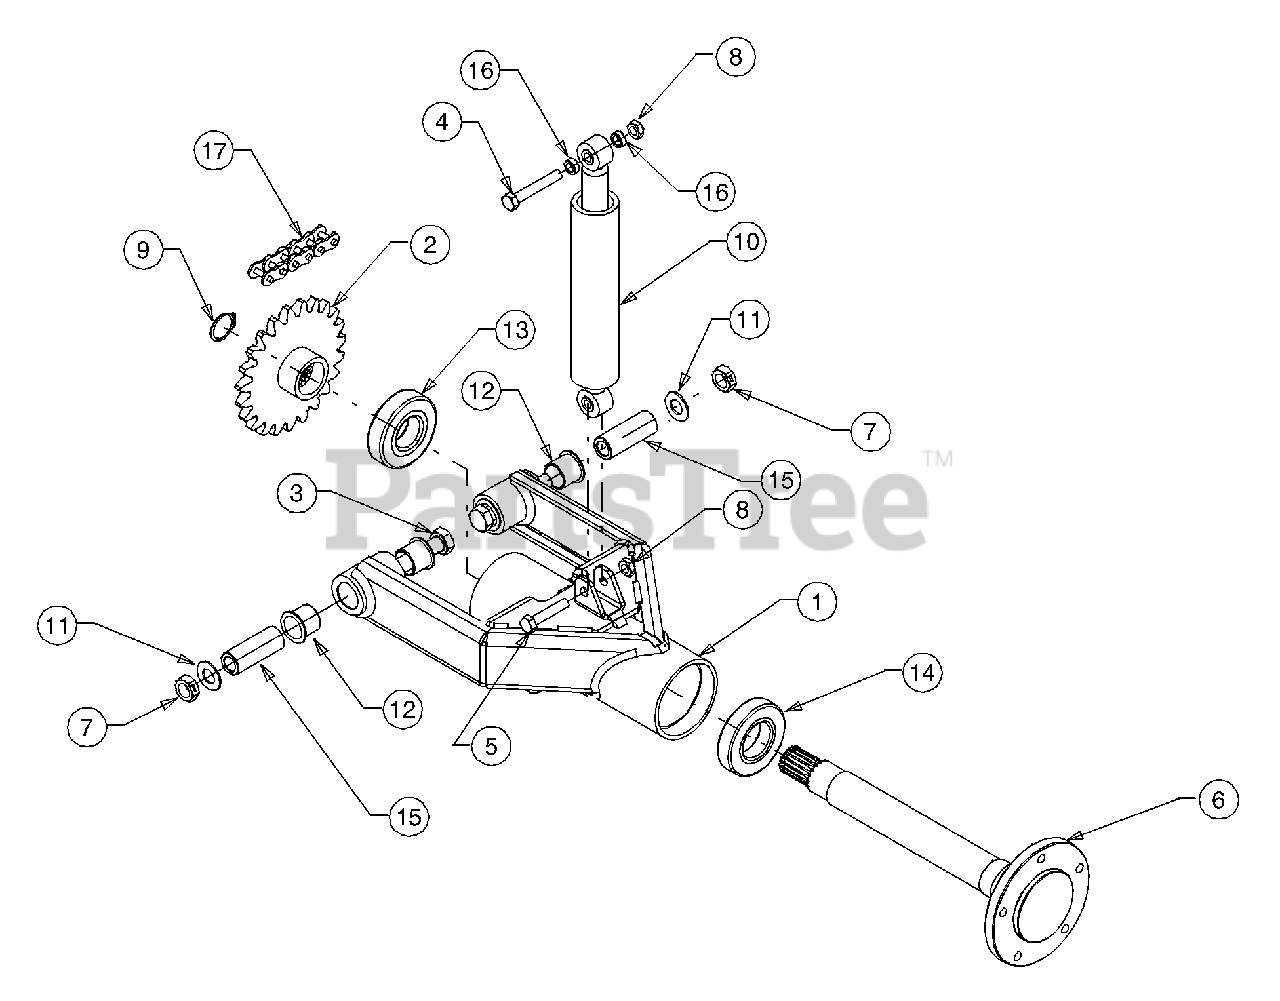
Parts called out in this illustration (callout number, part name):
1	Axle Support Assembly, Rear Weld
2	Sprocket Assembly, Rear, .75 - 23T
3	Screw, Hex, 5/8-18 x 3.5, Gr5
4	Screw, M10-1.25 x .65, Gr8
5	Screw, M10-1.25 x .50, Gr8
6	Axle Shaft, Rear Drive
7	Jam Nut, Nylon Lock, 5/8-18
8	Nut, Nylon Lock, M10 x 1.25
9	Retaining Ring, External, 1.14
10	Shock Absorber, 2.88 Stroke
11	Washer, Flat, .65 x 1.25 x .075
12	Bearing, Flange, 1.0 x 1.125 x 1.0
13	Ball Bearing, Internal Axle
14	Ball Bearing, External Axle
15	Spacer, .63 x 1.0 x 2.594
16	Spacer, Shock
17	Chain, #60 x 97 Pitch
